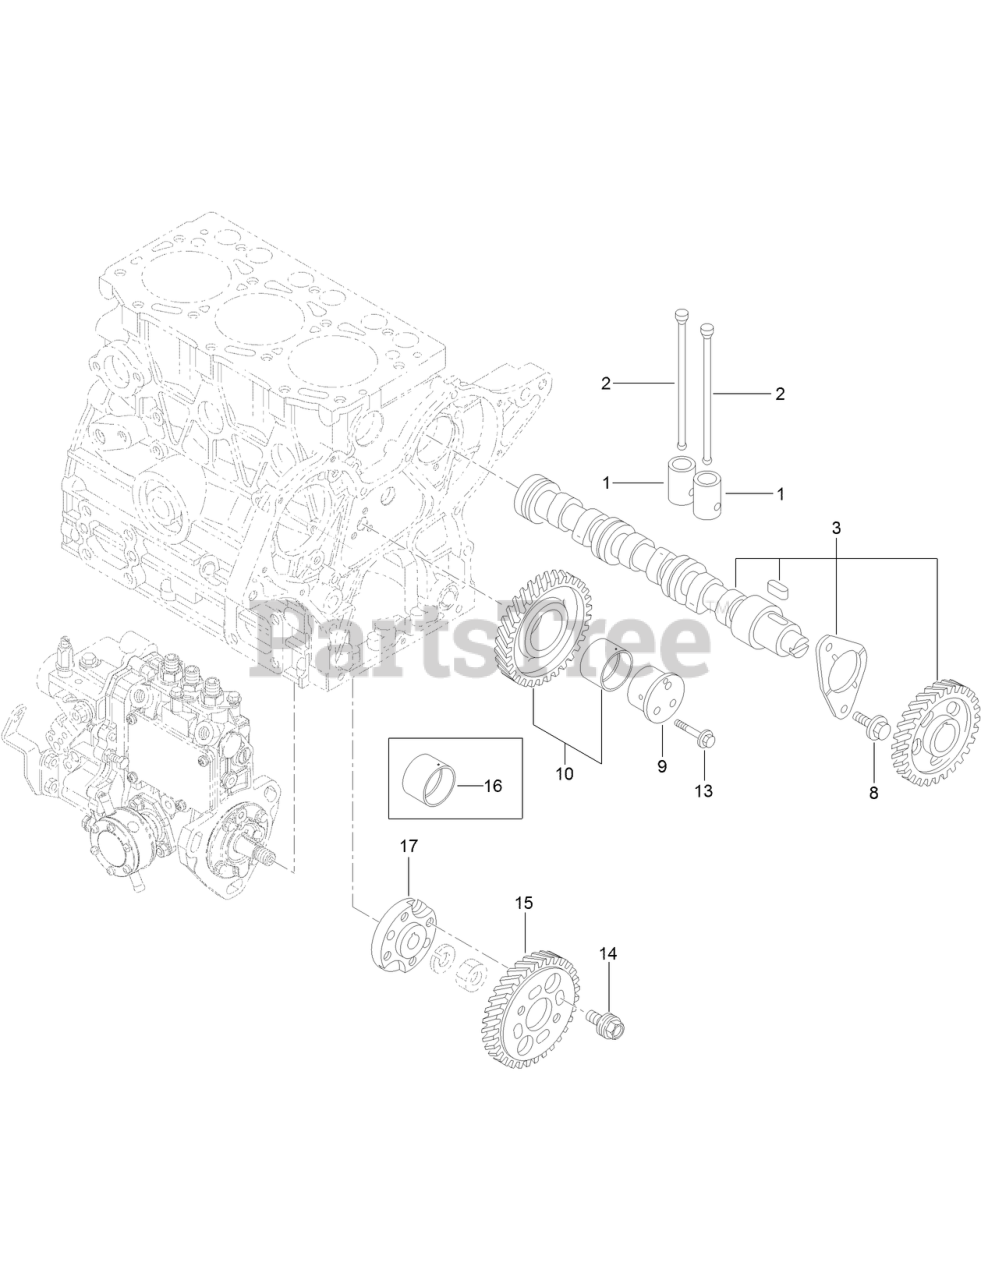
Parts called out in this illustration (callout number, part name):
1	TAPPET
2	PUSH-ROD
3	CAMSHAFT ASM
9	SHAFT-IDLE
10	GEAR ASSY-IDLE
15	GEAR-PUMP
16	BUSH-IDLE GEAR
17	FLANGE
